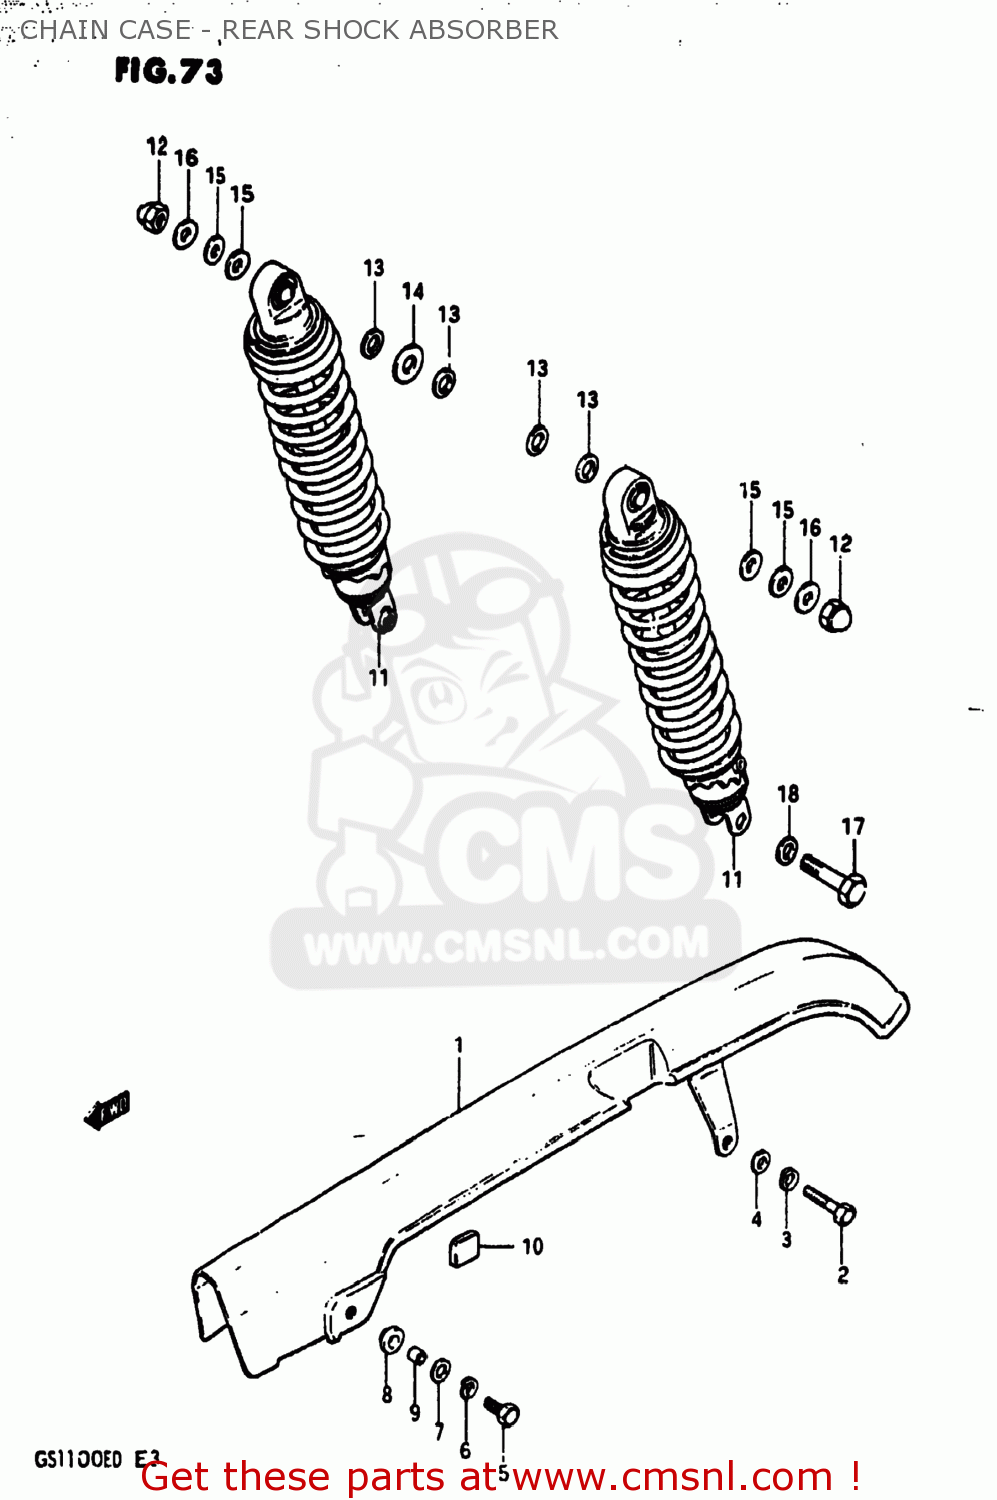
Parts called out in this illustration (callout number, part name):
1	CASE,CHAIN
2	BOLT
3	LOCK WASHER
4	WASHER
5	BOLT
6	LOCK WASHER
7	WASHER
8	CUSHION
9	SPACER(6.2X8.3X5.7)
10	CAP
11	ABSORBER ASSEMBLY,REAR SHOCK
12	NUT, LOWER LH
13	WASHER
14	WASHER (12.5X24X3.2)
15	WASHER
16	WASHER(10.5X24X3.2)
17	BOLT(10X36)
18	WASHER
